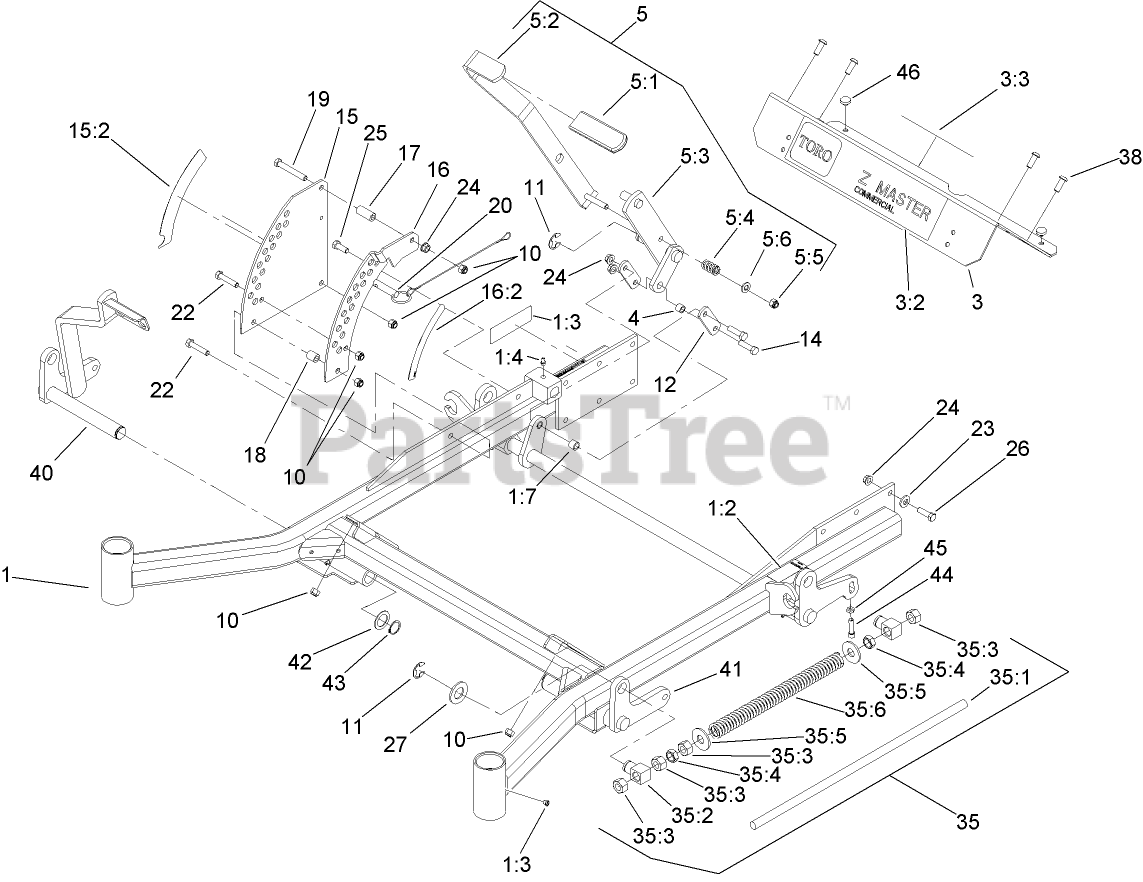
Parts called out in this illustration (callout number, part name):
1	FRAME ASM
1:2	Decal-Brake, Parking
1:4	FITTING-GREASE
1:7	Bushing
3	FOOTREST
3:3	DECAL-WARNING
4	Bushing
5	DECK LIFT HANDLE ASM
5:1	GRIP-LEVER, LIFT
5:2	LEVER-LIFT
5:3	ARM-LIFT, DECK
5:4	SPRING-COMPRESSION
5:5	NUT-LOCK, NI
5:6	WASHER-FLAT
10	NUT-LOCK, NI
11	RING-RETAINING, EXT
12	ARM-LIFT, DECK
14	SCREW-HH
15	PLATE-DECK LIFT, OUTER
15:2	Decal-Height, Deck
16	PLATE-DECK LIFT, INNER
16:2	Decal-Height, Deck
17	BUSHING-LEVER, LIFT
18	BUSHING-LEVER, LIFT
19	SCREW-HH
20	Hitch Pin ASM
22	SCREW-HH
23	WASHER-BELLEVILLE
24	NUT-HHF, WHIZ
25	SCREW-HH
26	SCREW-HH
27	WASHER-FLAT
35	Front Frame Spring ASM
35:1	ROD-LIFT, DECK
35:2	SWIVEL-DECK MOUNT, REAR
35:3	NUT-HEX
35:4	NUT-JAM
35:5	WASHER-FLAT
35:6	SPRING-SUPPORT, DECK
38	SCREW-HSBH
40	LIFT-DECK, RH FRONT
41	LIFT-DECK, LH
42	WASHER-SPACER
43	RING-RETAINING
44	SCREW-HSH
45	NUT-JAM
46	BUMPER
